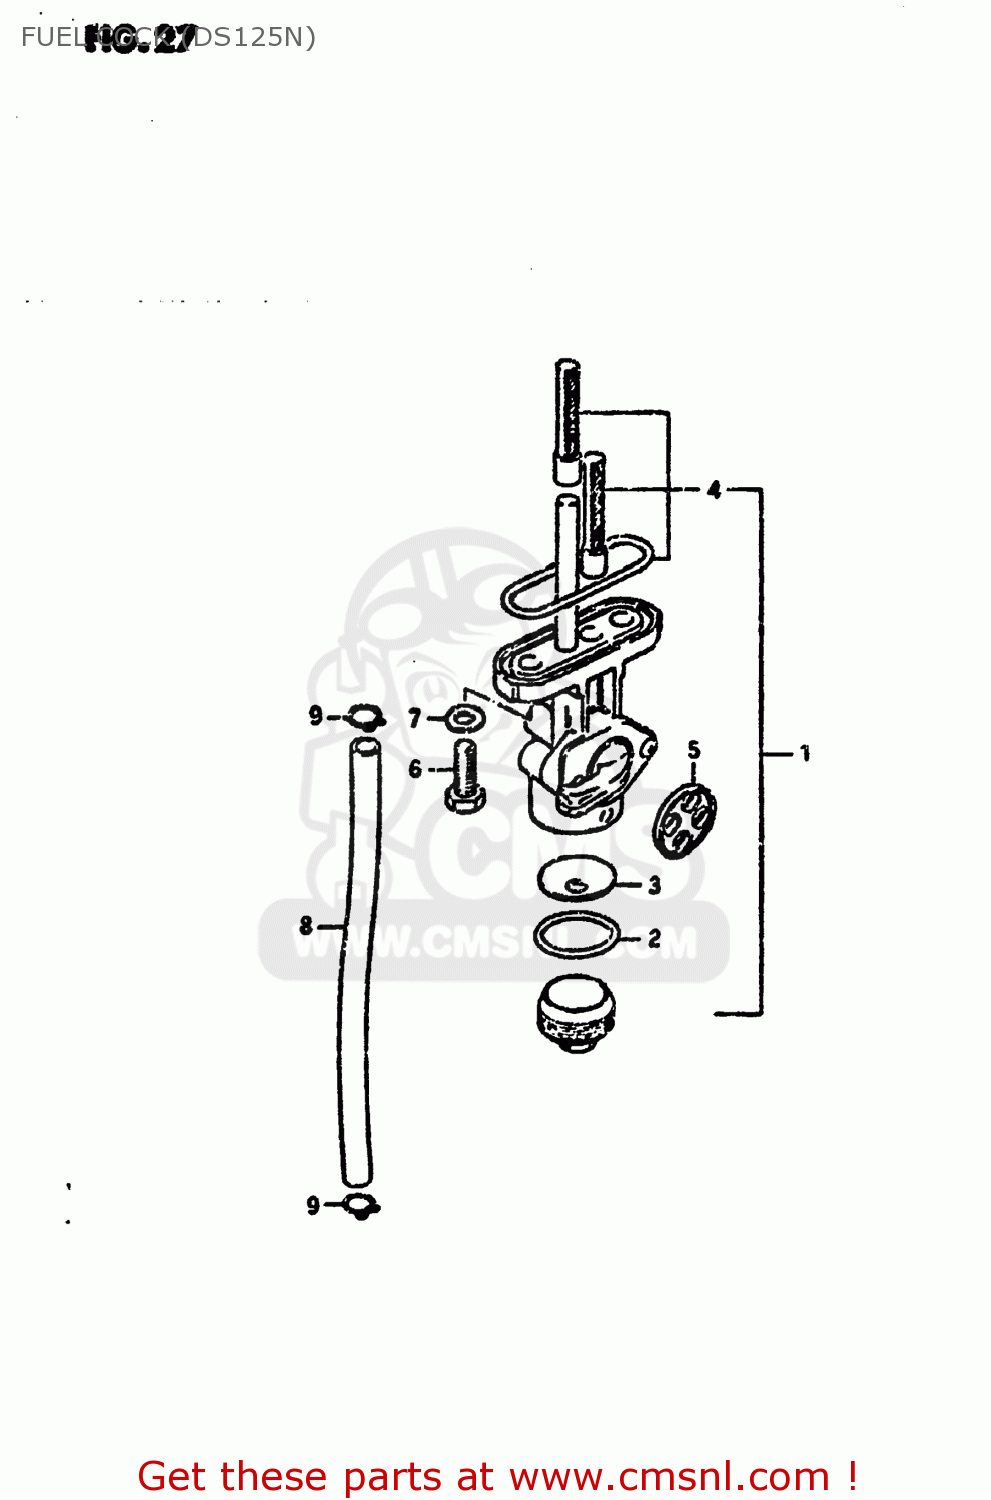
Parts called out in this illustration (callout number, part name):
1	COCK ASSEMBLY,FUEL
2	GASKET,FILTER (NAS)
3	NET,STRAINER
4	FILTER SET,FUEL COCK
5	GASKET,LEVER (NAS)
6	BOLT L:16
7	GASKET
8	HOSE
9	CLIP
